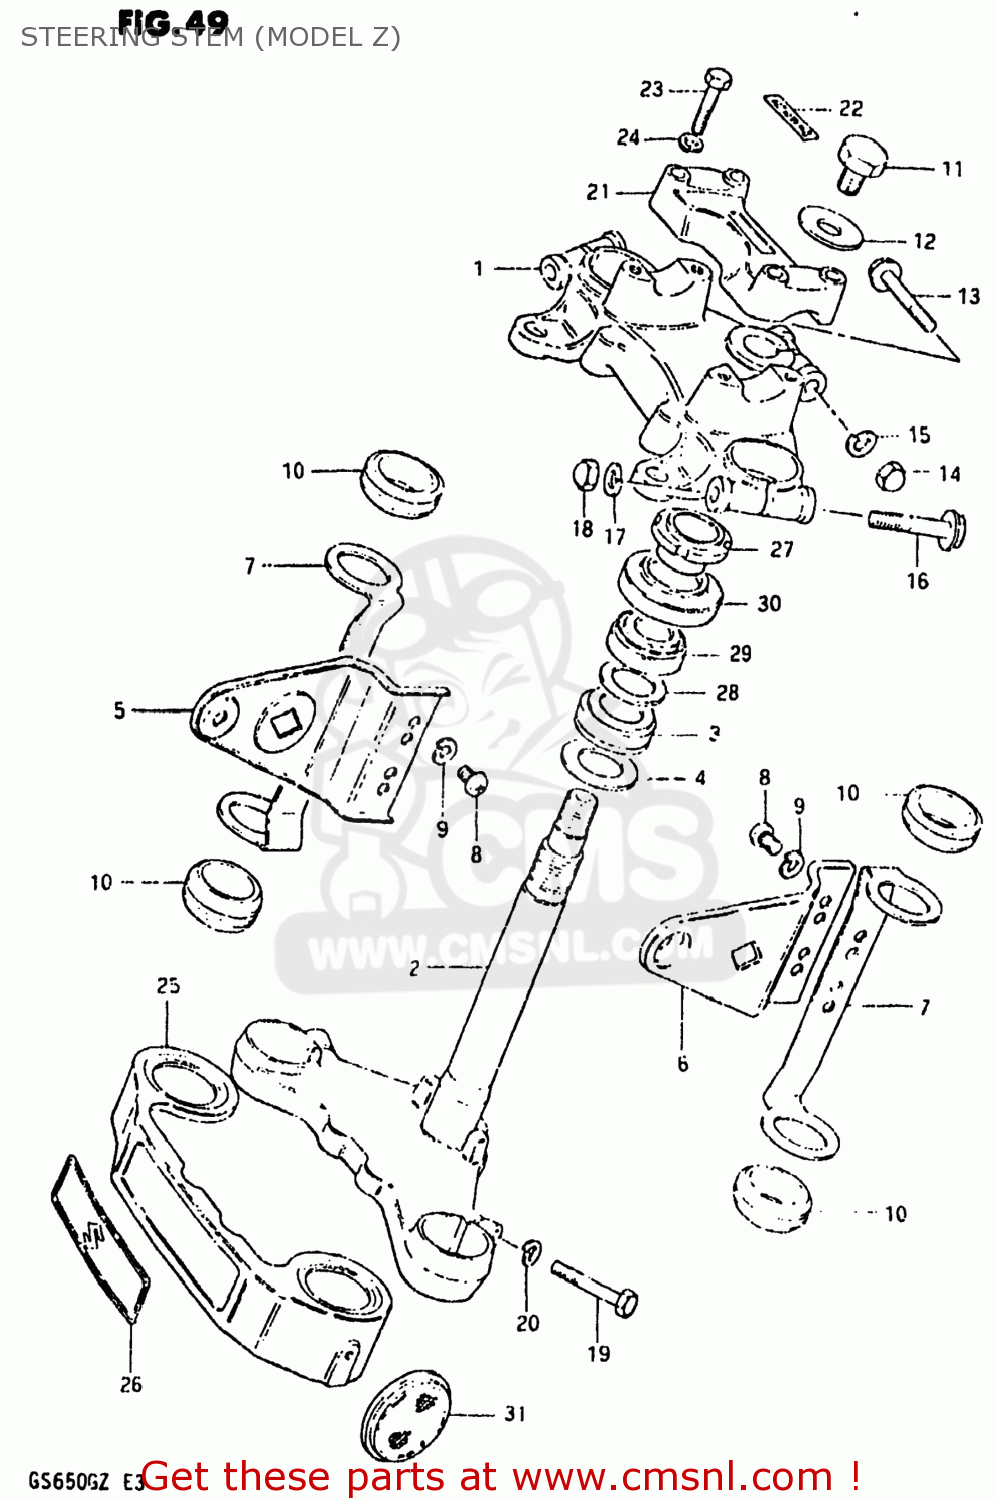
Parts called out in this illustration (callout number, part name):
1	HEAD,STEERING STEM
2	STEM,STEERING
3	BEARING
4	WASHER,THRUST
5	BRACKET,HEADLAMP,RIGHT
6	BRACKET,HEADLAMP,LEFT
7	FRAME,HEAD LAMP BRACKET
8	SCREW
9	LOCK WASHER
10	CUSHION,HEADLAMP BRACKET
11	BOLT(12X20)
12	WASHER
13	BOLT
14	NUT,M8X1.25X12
15	LOCK WASHER
16	BOLT 10X55
17	LOCK WASHER
18	NUT
19	BOLT 10X40
20	LOCK WASHER
21	HOLDER,HANDLEBAR
22	EMBLEM,HANDLE CLAMP
23	BOLT
24	LOCK WASHER
25	COVER,FRONT FORK
26	EMBLEM
27	NUT,STEERING STEM
28	WASHER(18.5X24X1)
29	TAPER,ROLLER BEARING
30	DUST SEAL,STEERING,UPPER
31	REFLEX REFLECTOR,RR
